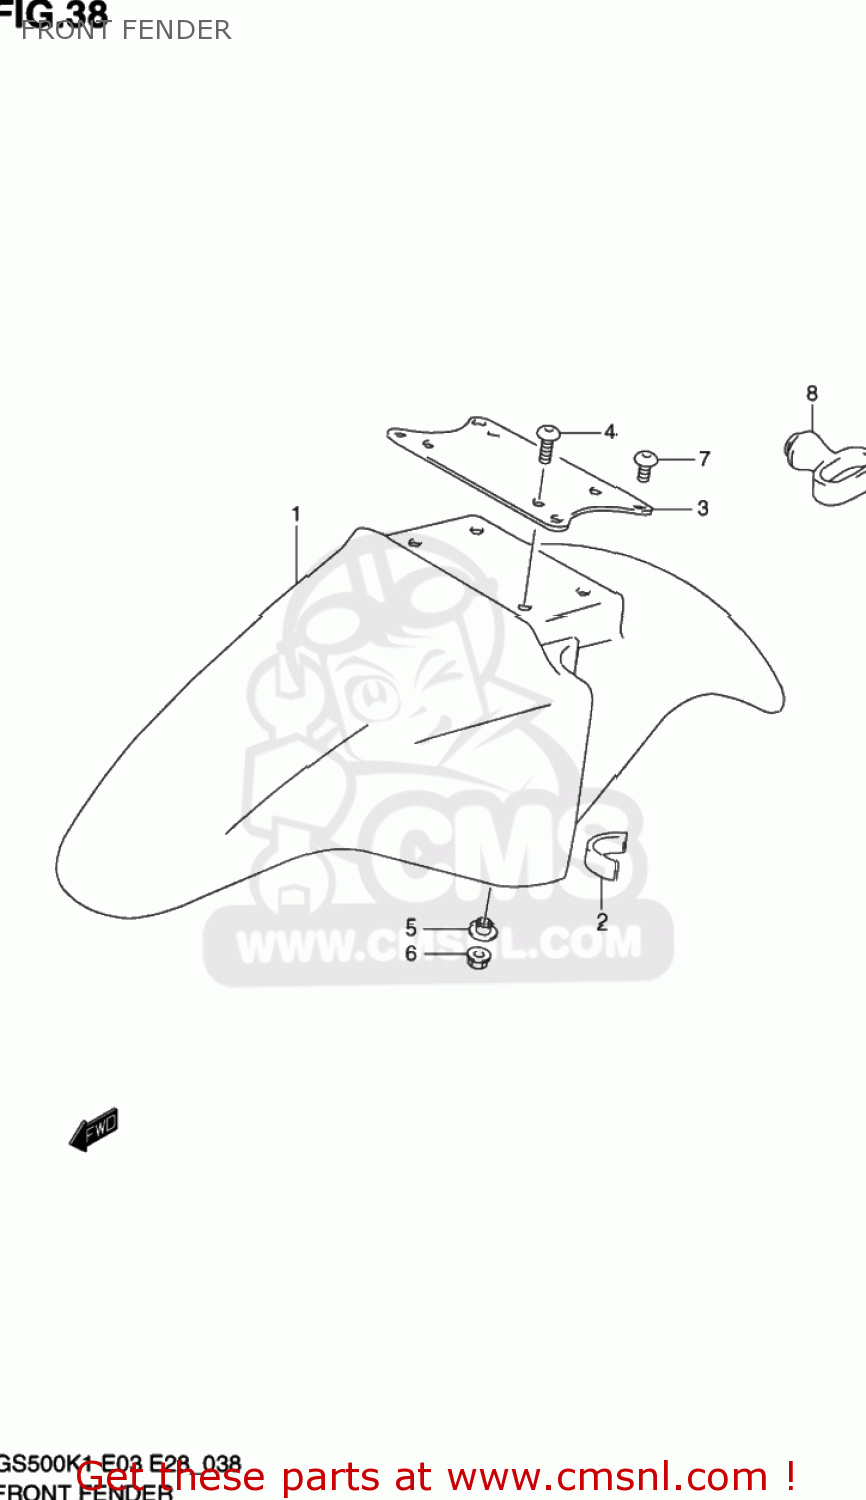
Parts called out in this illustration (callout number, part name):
1	FENDER,FRONT
2	CUSHION,FR FENDER
3	BRACE,FR FENDER
4	SCREW(5X18)
5	WASHER
6	NUT
7	SCREW(6X12)
8	GUIDE,CABLE
